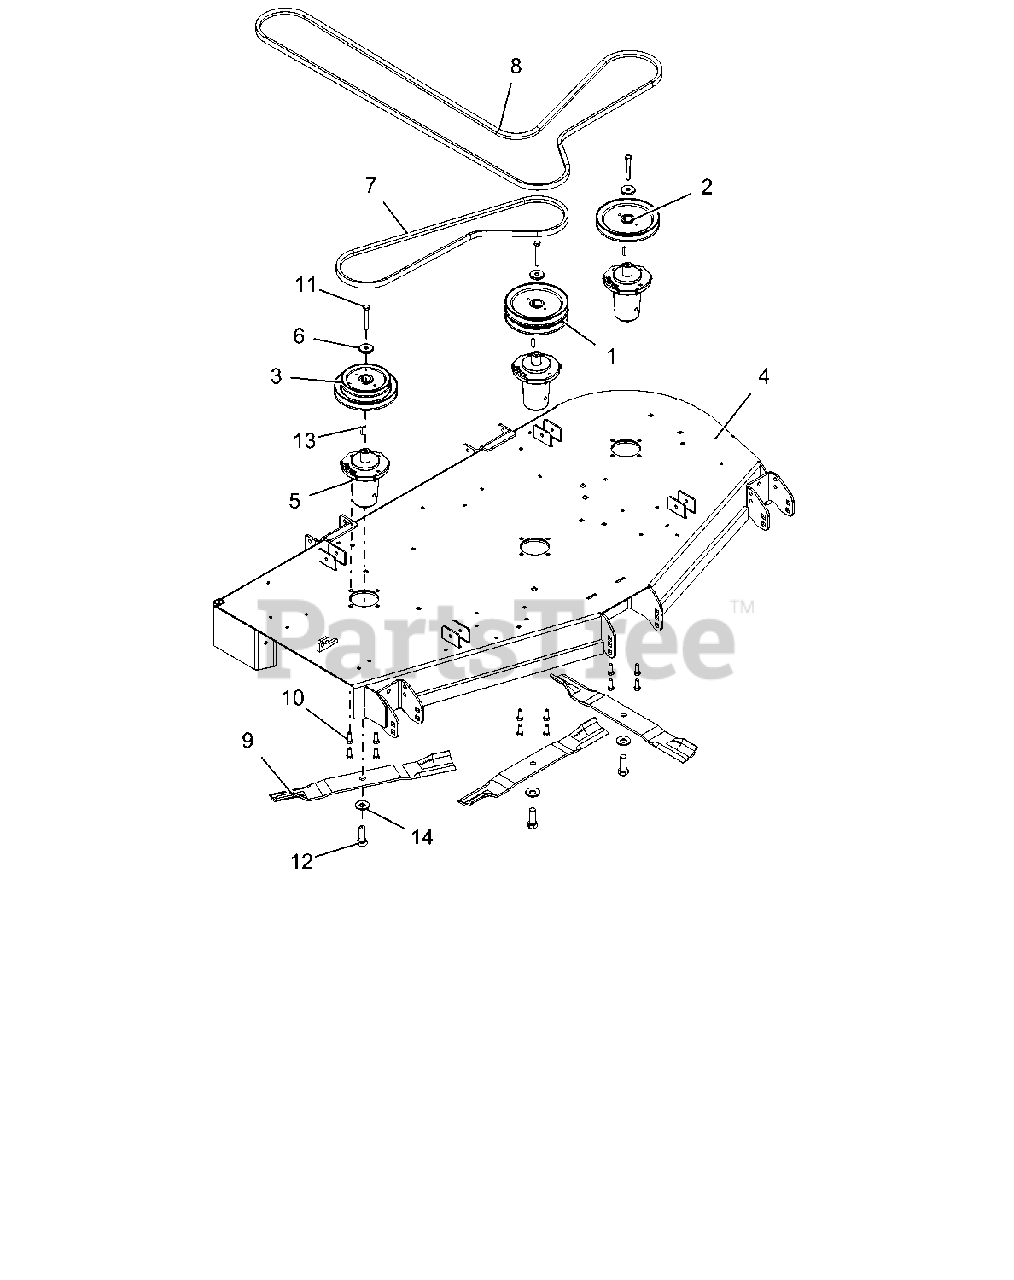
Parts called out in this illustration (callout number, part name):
1	PULLEY, DOUBLE 1"ID X 6.75"OD-BLACK
2	PULLEY, V-1" ID X 6.75" OD-BLACK
3	PULLEY, DOUBLE -1" ID X 6.75" & 5.25" OD
4	WLDMT, 60" SIDE DISCH DECK
5	ASM, SPINDLE - G3500
6	RETAINER, SHEAVE SPINDLE
7	BELT, B 63.00 RAW COGGED
8	V-BELT, HB WRAPPED
9	BLADE, MOWER 60"
10	BLT-HEX .38-16X1.00 GR5 YWZC EP30
11	BLT-HEX .38-16X2.75 GR8 YWZC
12	BLT-HEX .625-18X1.75 GR8 YWZC
13	KEY-SQ .250X.250X1.00 RC 40-50
14	WSHR, BLVL-.63X1.625X.14
